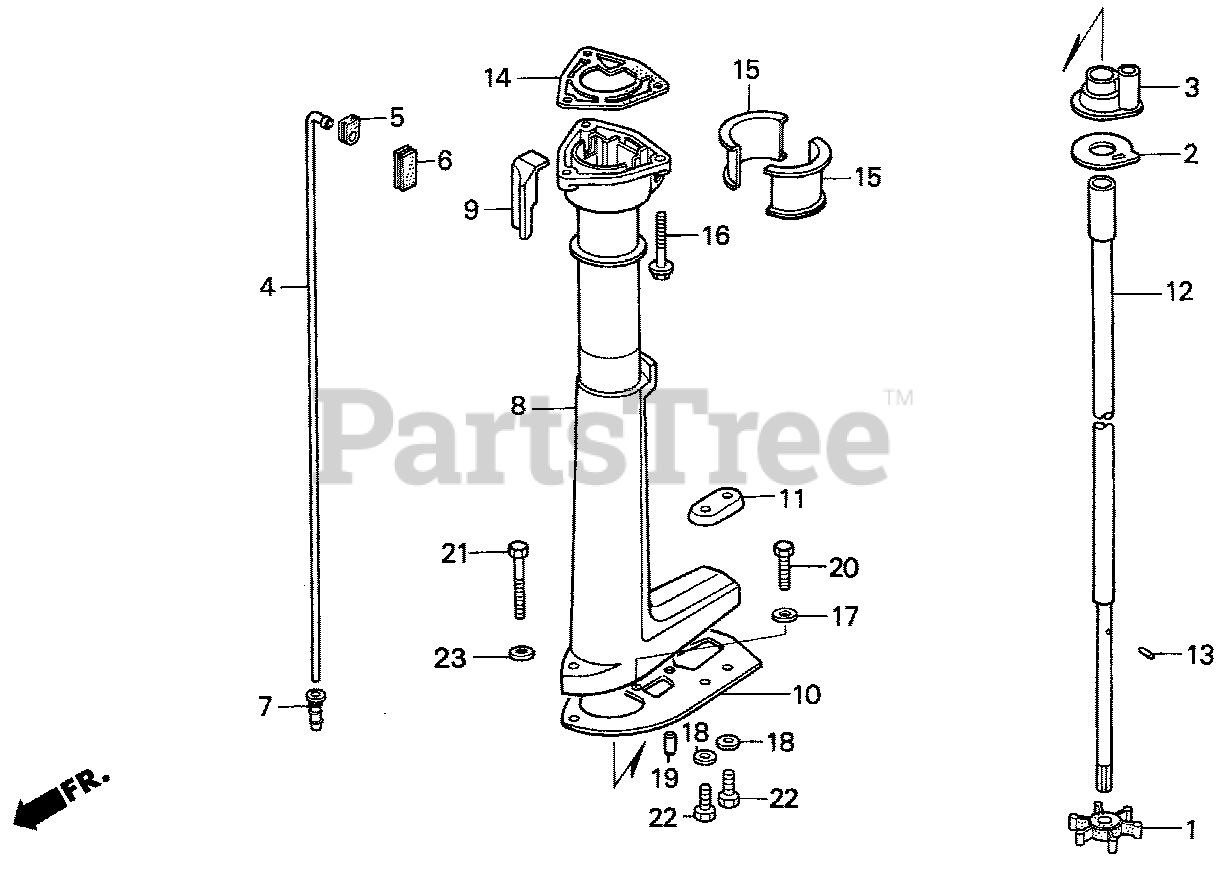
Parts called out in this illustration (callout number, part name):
1	IMPELLER, WATER PUMP
2	COVER, IMPELLER
3	HOLDER, IMPELLER COVER
4	TUBE, WATER
5	RUBBER A, WATER SEAL
6	RUBBER B, WATER SEAL
7	GROMMET, WATER PUMP
8	CASE, EXTENSION *NH282MU* (OYSTER SILVER METALLIC-U)
9	GUIDE, EX.
10	PLATE, CAVITATION *NH282MU* (OYSTER SILVER METALLIC-U)
11	METAL, ANODE
12	SHAFT, VERTICAL
13	PIN, VERTICAL SHAFT
14	GASKET, CASE (UPPER)
16	BOLT, FLANGE (6X32)
17	WASHER, PLAIN (6MM)
18	WASHER, PLAIN (6MM)
19	PIN, DOWEL (8X17)
20	BOLT, HEX. (6X12)
21	BOLT, HEX. (6X35)
22	BOLT, HEX. (6X16)
23	WASHER, PLAIN (6MM)
